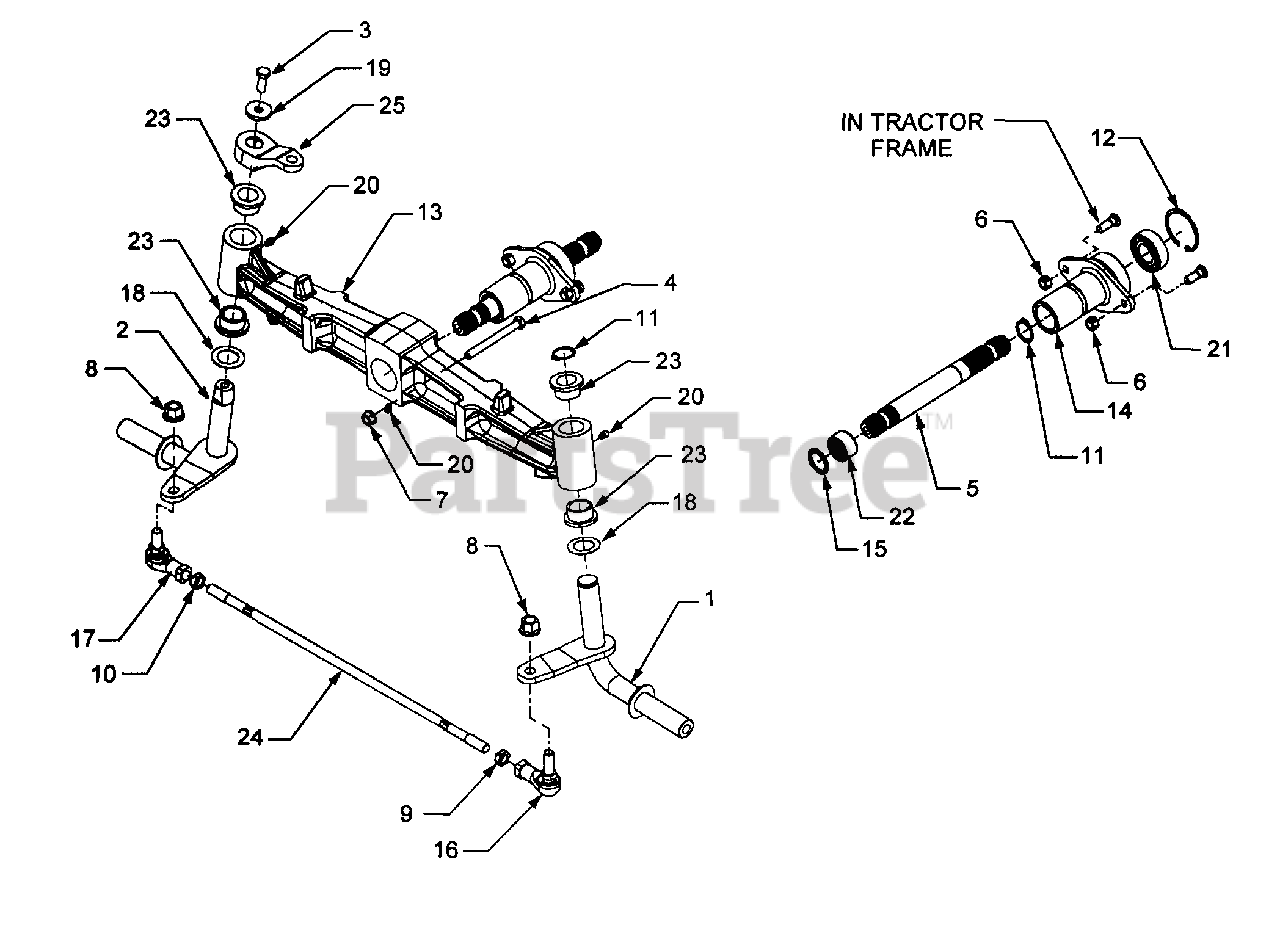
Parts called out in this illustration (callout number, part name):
1	Axle, RH Steering
2	Axle, LH Steering
3	Screw, Hex Cap 3/8-24 x 1.0 GR8
4	Screw, Hex Cap 3/8-16 x 3.5 GR5
5	Shaft, Splined
6	Nut, Hex Center Lock, 3/8-24
7	Nut, Hex Flange Lock, 3/8-16
8	Nut, Hex Flange Lock, M12 x 1.75
9	Nut, Hex - RH, M12 x 1.75
10	Nut, Hex - LH, M12 x 1.75
11	Snap Ring, 1.0 Dia. Shaft
12	Retaining Ring, Internal, 2.0
15	Seal, Grease, 1.31 x 1.0
16	Ball Joint, 12MM x 1.75 RH
17	Ball Joint, 12MM x 1.75 LH
18	Washer, Flat, 1.03 x 1.62 x .030
19	Washer, Flat, .406 x 1.25
20	Fitting, Lube, 3/16 Drive
21	Bearing, Ball
22	Bearing, Needle
23	Bearing, Flange
24	Tie Rod, M12 x 1.75 RH & LH
25	Steering Arm
